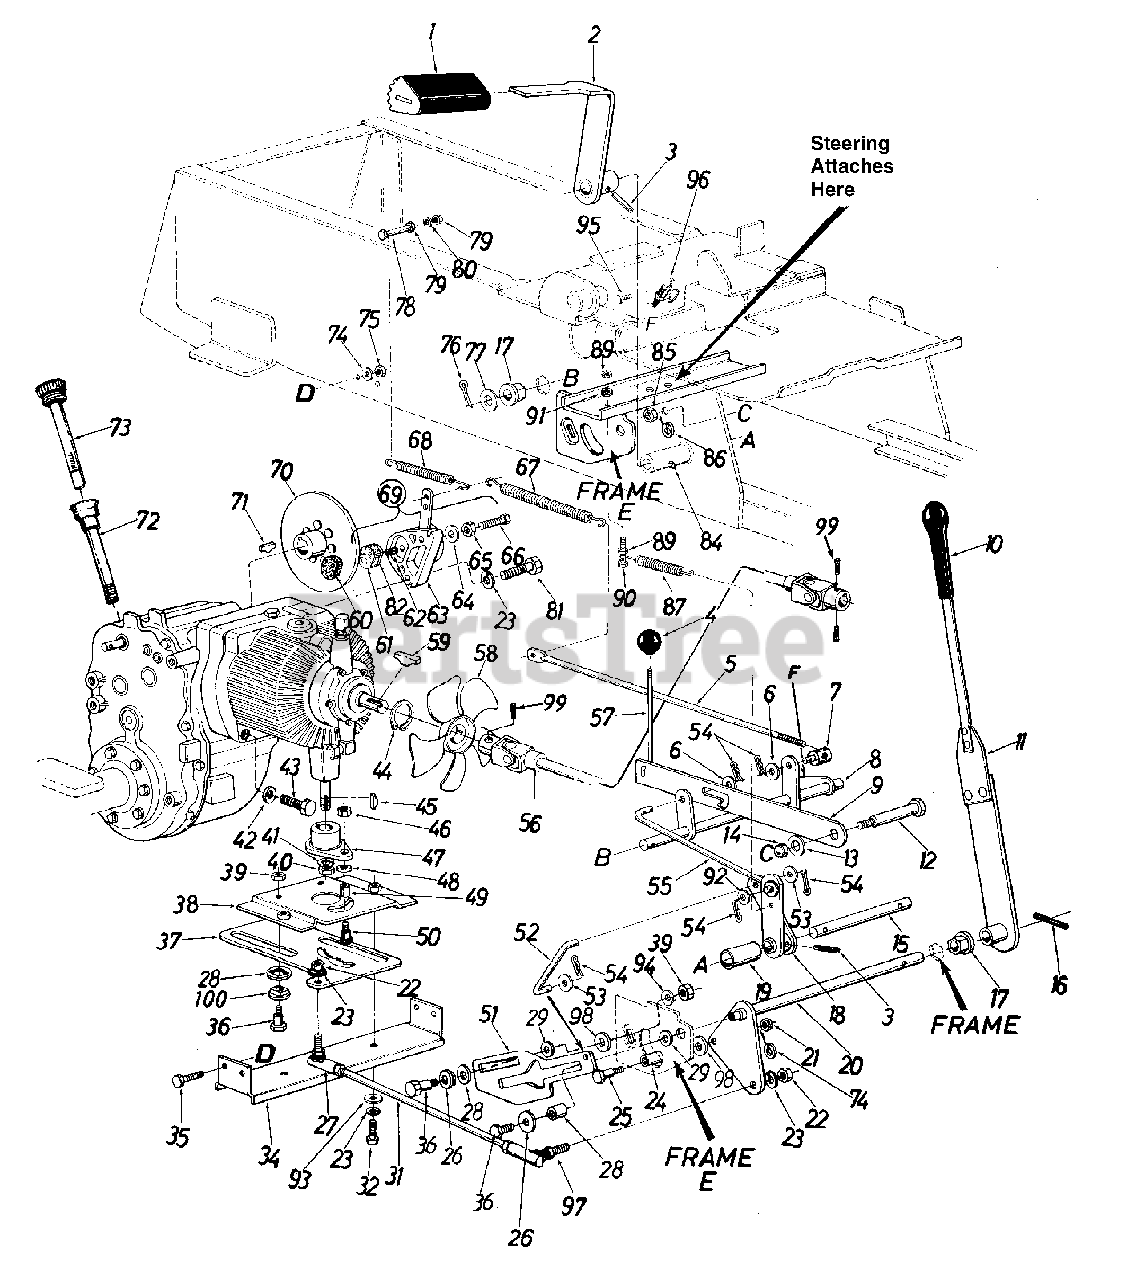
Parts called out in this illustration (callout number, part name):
1	Foot Pad
4	Ball Knob-Brake
5	Brake Rod
6	Fl-Wash. .375" I.D. x 1.00" O.D. x .030"
7	Ferrule
8	Brake Transfer Shaft Ass'y.
9	Parking Brake Cam
11	Control Arm Ass'y. Comp.
12	Shld. Bolt .62" Dia. x 2.75" Lg.
13	Fl-Wash. .460" I.D. x 1.24" O.D. x .06"
14	Push Speed Nut for .625" Dia.Shaft
15	Brake Pivot Shaft
16	Spring Pin Spiral 1/4" Dia. x 1.50" Lg.
17	Hex Flange Brg. Plastic .62" I.D.
18	Brake Lever Ass'y.
19	Spacer
20	Control Handle Shaft Ass'y.
21	Hex Cent. L-Nut 5/16-18 Thd.
22	Hex Nut 3/8-24 Thd.
23	L-Wash. 3/8" I.D.
24	Spacer
25	Shoulder Bolt
26	Fl-Wash. 7/16" I.D. x 1-3/8" O.D.
27	Ball Joint Ass'y. 3/8-24 Thd.-L.H.
28	Spacer
29	Fl-Wash. .325" I.D. x 1.25" O.D.
31	Tie Rod
32	Hex Bolt 3/8-16 x .75" Lg.
34	Support Channel
35	Hex Bolt 5/16-18 x .75" Lg.
36	Shld. Bolt .437" Dia. x .268"
37	Cam Plate
38	Slide Mtg. Plate Ass'y.
39	Hex Cent. L-Nut 5/16-18 Thd.
40	Hex Nut 1/2-13 Thd.
41	L-Wash. 1/2" I.D.
42	Fl-Wash. .385" I.D. x .87" O.D. x .060"
43	Socket Hd. Scr. 3/8-16 x 2.75"Lg.
44	Snap Ring
45	#5 Hi-Pro Key 1/8" x 5/8" Dia.
46	Hex Cent. L-Nut 1/4-20 Thd.
47	Pintle Plate Ass'y.
48	Fl-Wash. .281" I.D. x .50" O.D. x .063"
49	Needle Brg. .31" I.D. x .50" O.D. x
50	Shld. Bolt .31" Dia. x .500
51	Neutral Control Slide
52	Neutral Control Rod
53	Fl-Wash. .312" I.D. x .630" O.D. x
54	Hairpin Cotter
55	Brake Link Rod Ass'y.
56	Universal Drive Shaft Comp.
57	Parking Brake Link
58	Fan Ass'y.
59	#61 Hi-Pro Key 3/16 x 5/8" Dia.
60	Lining-Brake
61	Lining-Brake
62	Actuator Pin
63	Housing with Lever and Pin
65	Nut
66	Adjustment Pin
67	Extension Spring .50" O.D. x 6.5" Lg.
68	Extension Spring (Brake Return)
69	Disc Brake Ass'y. Comp.
70	Brake Disc Ass'y.
71	Hi-Pro Key 3/16 x 3/4" Dia.
72	Dipstick Tube Ass'y.
73	Dipstick Ass'y.
74	L-Wash. 5/16" I.D.
75	Hex Nut 5/16-18 Thd.
76	Cotter Pin 1/8" Dia. x 1.00" Lg.
77	Fl-Wash. .635" I.D. x 1.00" O.D. x
78	Hex Scr. 1/4-20 x 2.50" Lg.
79	Hex Nut 1/4-20 Thd.
80	L-Wash. 1/4" I.D.
81	Hex Scr. 3/8-16 x 1.25" Lg.
82	Backing Plate
84	Grease Fitting
85	Hex Nut 7/16-20 Thd.
86	L-Wash. 7/16" I.D.
87	Extension Spring
89	Hex Nut 1/4-20 Thd.
90	Hex Bolt 1/4-20 x 1.25" Lg.
91	L-Wash. 1/4" I.D.
92	Fl-Wash.
93	Fl-Wash. .38" I.D. x 1.25" O.D.
94	Bell-Wash.
95	Truss Mach. Scr. #10 x .5" Lg.
96	Safety Switch
97	Ball Joint Ass'y. 3/8-24 Thd.-R.H.
98	Fl-Wash. .32" I.D. x .6" O.D.
99	Set Screw 5/16-18 x .38" Lg.
100	Thrust Washer
